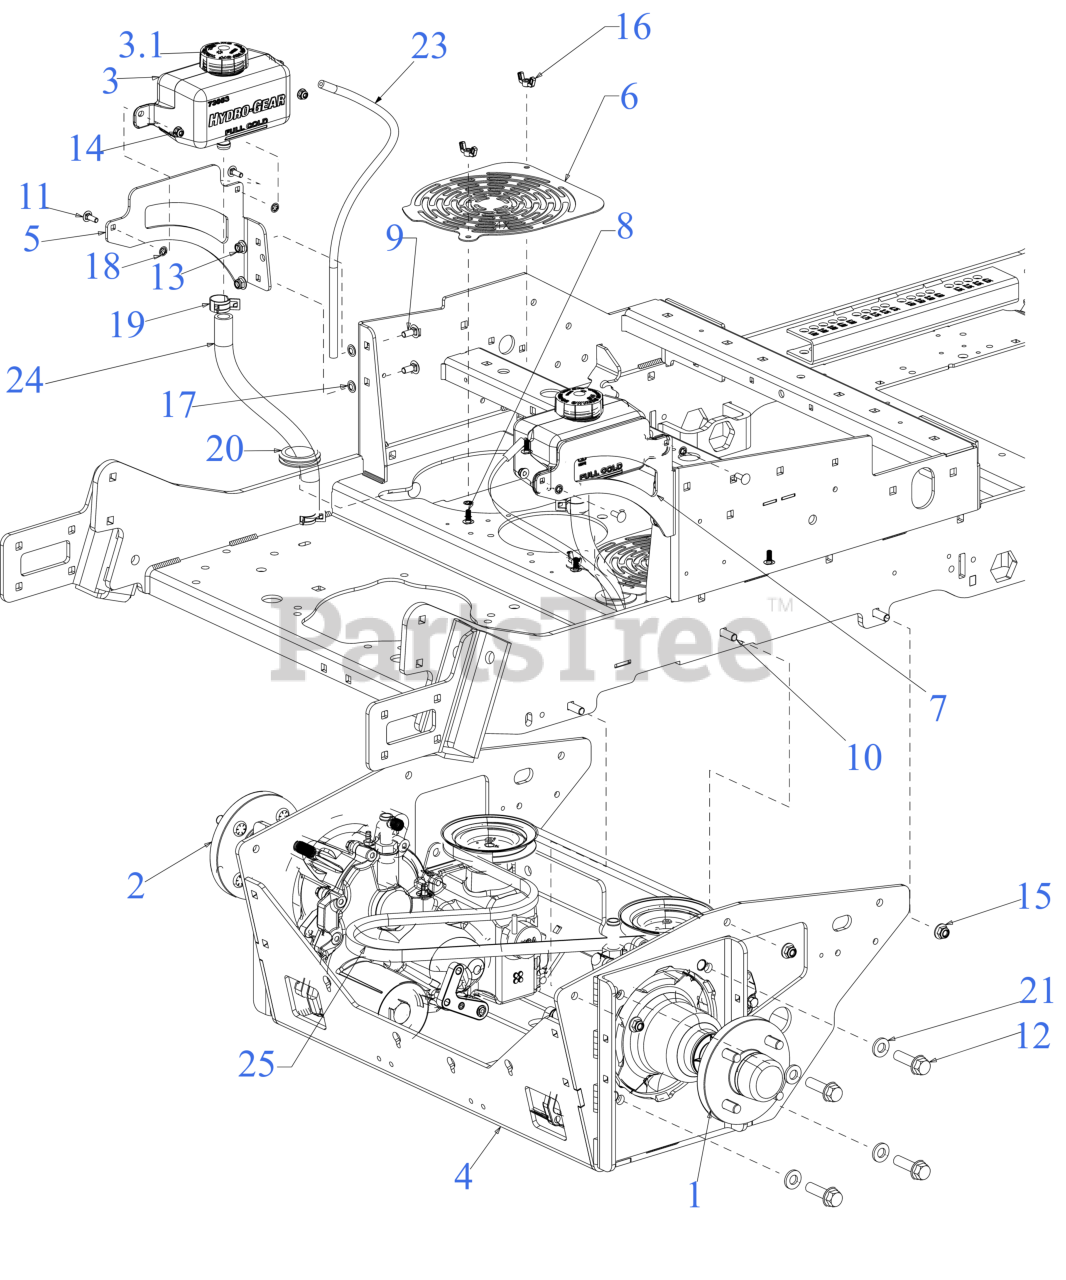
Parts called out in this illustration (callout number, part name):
1	TRANSMISSION (RH)
2	TRANSMISSION (LH)
3	1L EXPANSION TANK
3.1	CAP-EXPANSION TANK
4	SUB FRAME BRACKET
5	TANK MOUNT BRACKET (LH)
6	TRANSMISSION COVER PLATE
7	TANK MOUNT BRACKET (RH)
8	CARRIAGE BOLT 1/4-20 x .62
9	CARRIAGE BOLT 5/16-18 x .75
10	CARRIAGE BOLT 3/8-16 X1.25 GR5
11	SCREW 1/4-20 x .75 GR5
12	FLANGE BOLT 1/2-13:1.75:GR5
13	FLANGE LOCK NUT 5/16-18
14	FLANGE LOCK NUT
16	WING NUT 1/4-20
18	RETAINER-BOLT .25ID x .50OD
19	HOSE CLAMP
20	RUBBER GROMMET (1.50X2.13X.563)
21	FLAT WASHER .510 x 1.000 x .125
23	VENT HOSE 3/16 ID 45"LG
24	OIL HOSE 5/8 ID X 13.5 LG
25	V-BELT 65.58"
